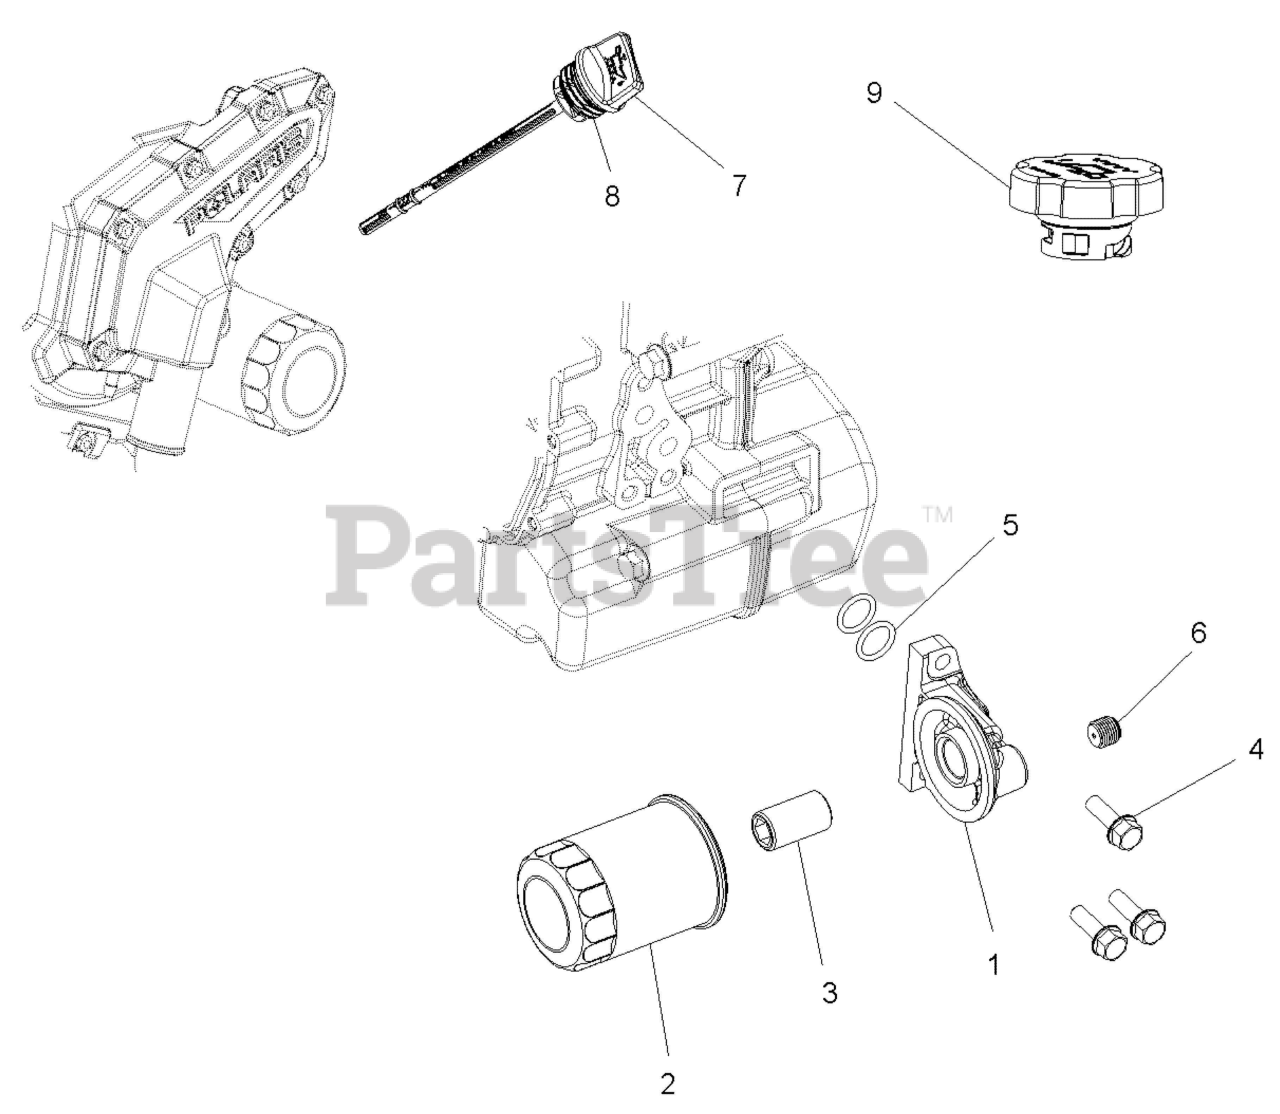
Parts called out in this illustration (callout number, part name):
1	ADAPTER, OIL FILTER, MACH
2	FILTER-OIL,10 MICRON,(12)
3	ADAPTOR, FILTER, STRAIGHT
5	O-RING-17.12X2.62
6	PLUG,HEX SCKT W/O-RING,M14X1.5
7	DIPSTICK-OIL FILL
8	O-RING-26.65X2.62,0600083
9	ASM-OIL FILL CAP
9	O-RING-FILL CAP
